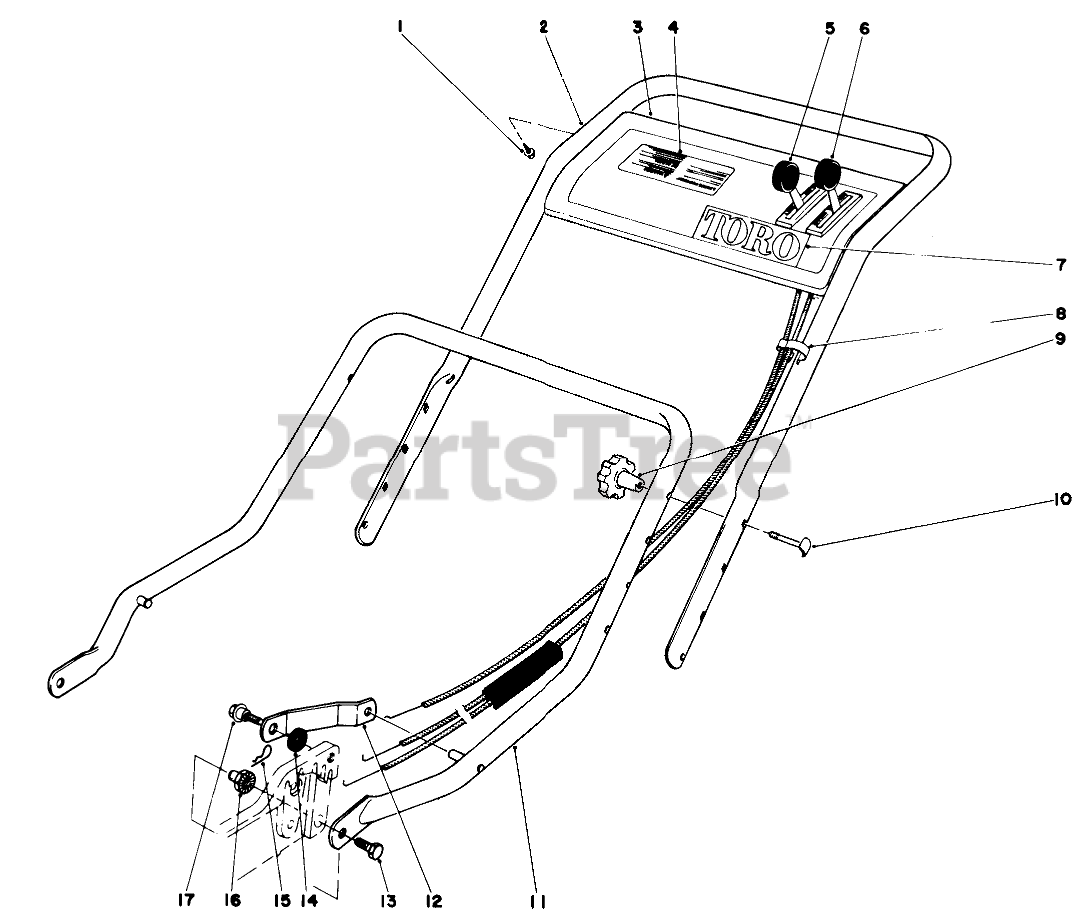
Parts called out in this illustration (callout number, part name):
1	SCREW-HWHTF
2	Upper Handle
3	Control Plate
4	Decal Control Plate
5	Control-Throttle
6	Control-Traction
7	TORO LOGO DECAL
8	BOWDEN CLIP
10	HANDLE SCREW
11	Lower Handle
12	HANDLE LATCH
13	SCREW-HH
14	SPACER
15	PIN-COTTER, HAIR
16	HANDLE PIVOT NUT
17	SCREW-SHOULDER
